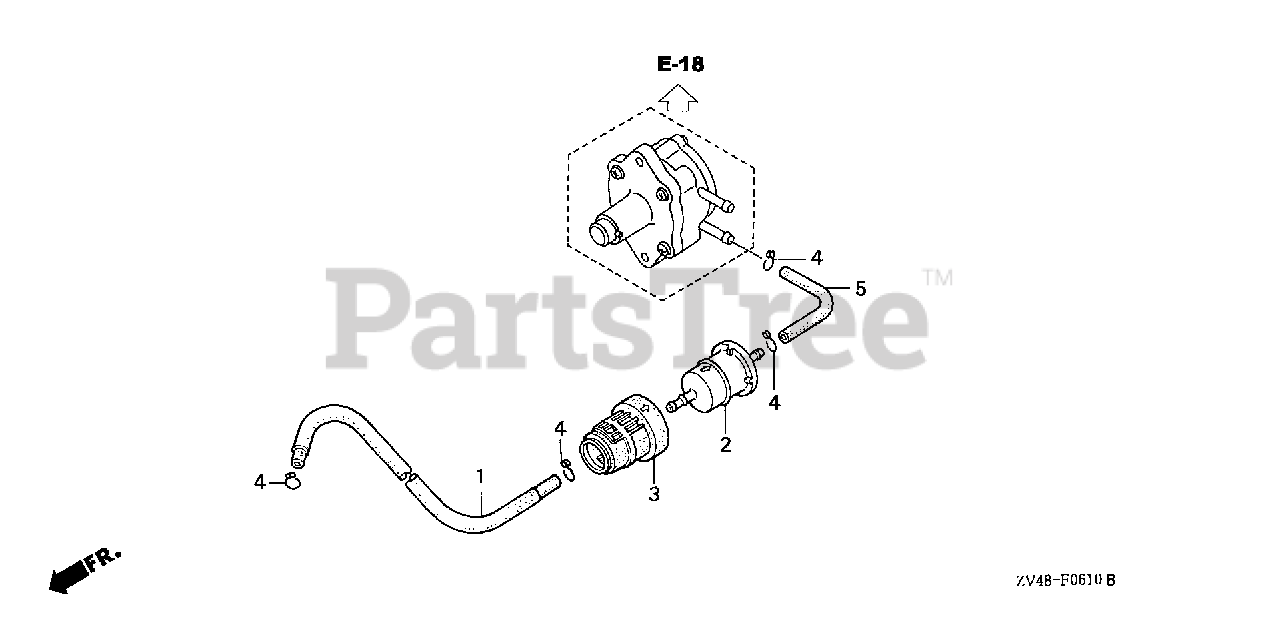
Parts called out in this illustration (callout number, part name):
1	TUBE, FUEL (B)
2	STRAINER, FUEL
3	SUSPENSION, STRAINER
4	CLIP, TUBE (B10)
5	BULK HOSE, FUEL (5.5X3000) (5.3X90)
